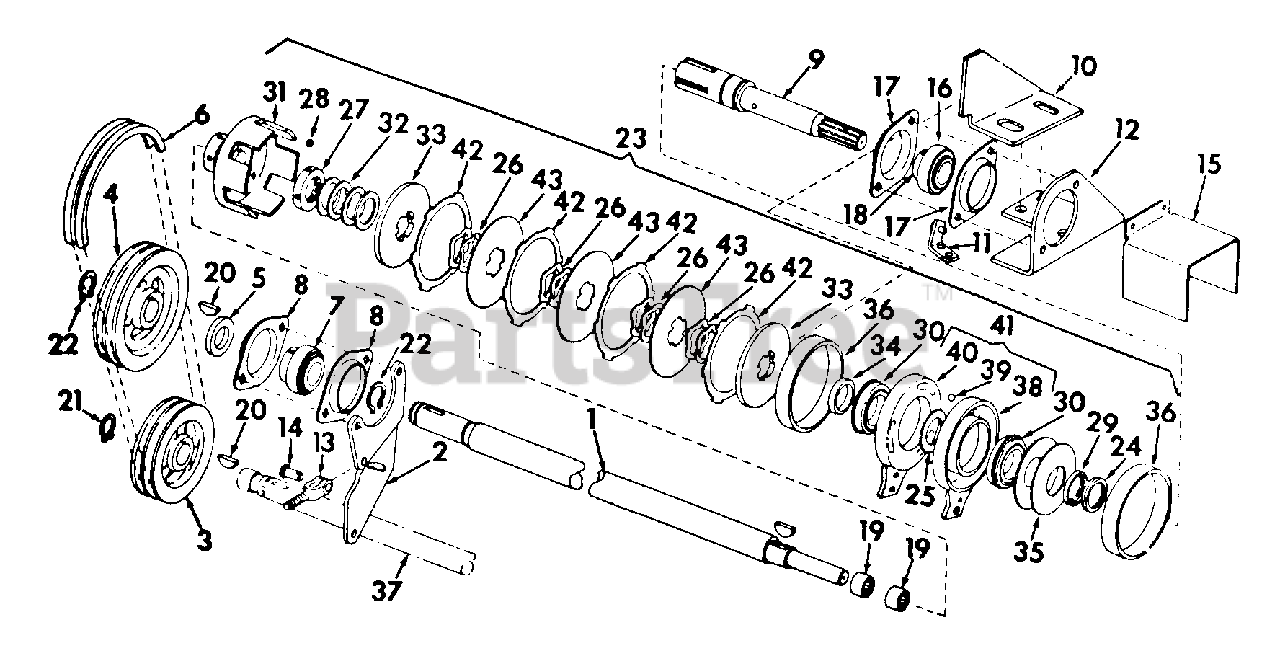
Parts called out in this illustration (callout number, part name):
1	SHAFT, PTO DRIVE
2	ADJUSTER, PTO SHAFT & PULLEY
3	PULLEY, PTO DRIVE
4	PULLEY, PTO DRIVEN
5	SPACER, PTO SHAFT
6	BELTS, MATCHED SET PTO DRIVE V
7	BEARING, PTO SHAFT FRONT BALL
9	SHAFT W/TWO BEARINGS
10	SUPPORT ASSY, INDEPENDENT PTO BRAKE BRACKET
11	BRACKET, CLUTCH CLEAT
12	SUPPORT, PTO SHAFT BRG, MTG BRACKET
13	YOKE ASSY, ADJUSTABLE
14	PIN, 3/8 X 1-3/32 ROD END
15	GUARD, PTO SHAFT
16	BEARING, PTO SHAFT REAR BALL
18	COLLAR W/SET SCREW LOCKING
19	BEARING, PTO IDLER SHAFT NEEDLE
20	KEY, 3/16 X 1 WOODRUFF 13
21	RING, DRIVE PULLEY RETAINING
22	RING, RETAINING
23	CLUTCH ASSY, INDEPENDENT PTO
26	SPRING, WAVE
30	BEARING, CAM
31	CUP ASSY, DRIVE
33	PLATE, PRESSURE
35	SPRING, LOAD
38	CAM, STATIONARY
39	BALL, 7/16 CR-STL
40	CAM, ACTUATING
41	KIT, ACTUATOR REBUILD
42	DISC FRICTION
43	DISC SEPARATOR
